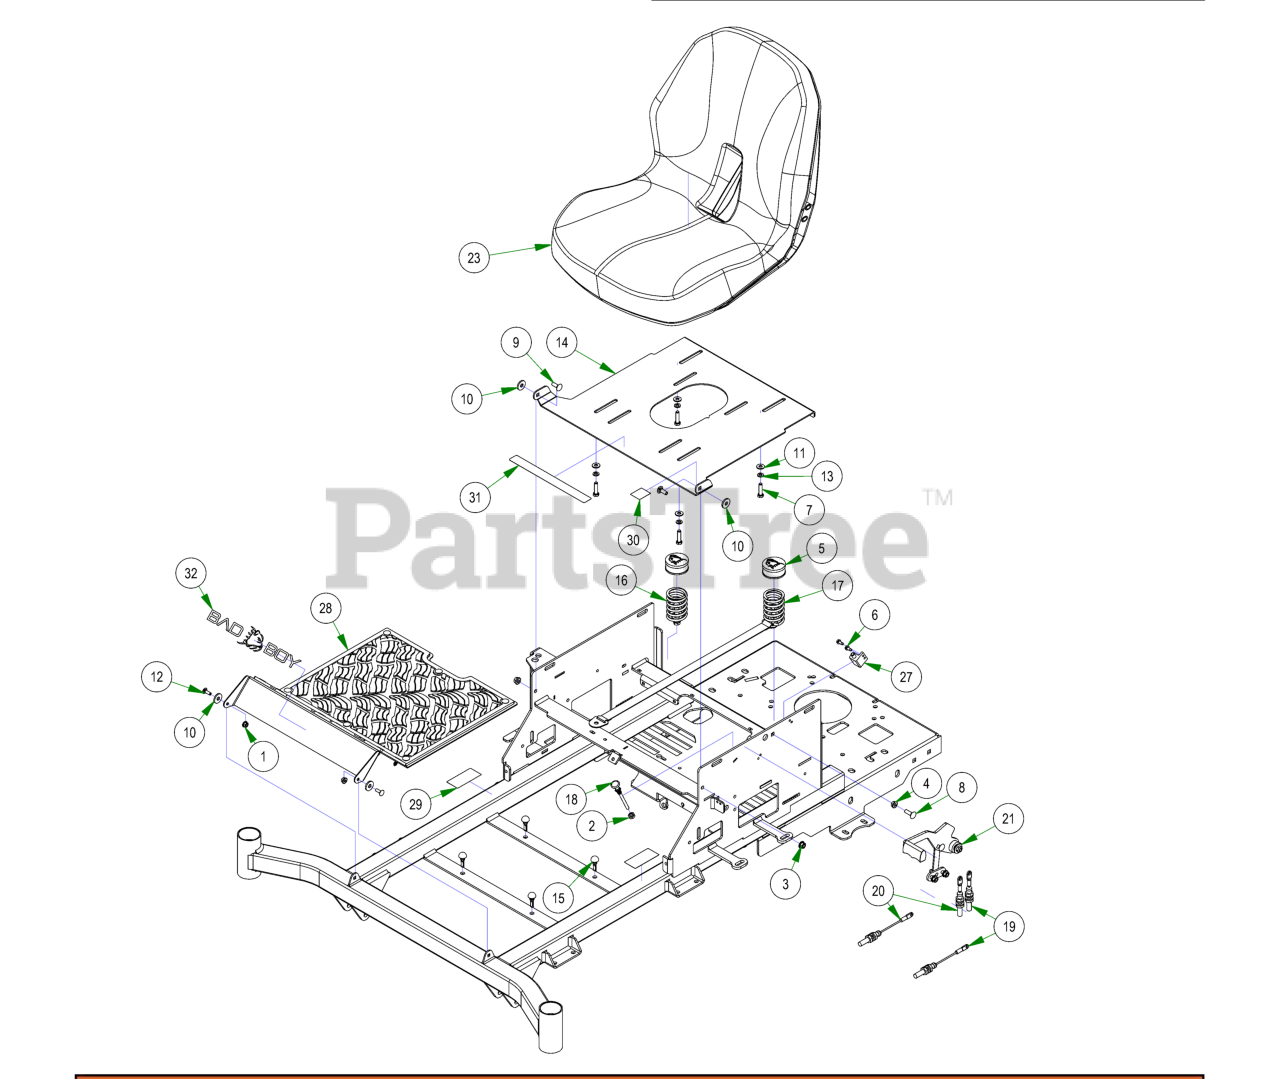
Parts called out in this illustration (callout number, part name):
1	1/4-20 NYL INSERT FLANGE LOCKNUT ZINC
2	3/8-24 HEX NUT ZINC YELLOW
3	5/16-18 NYLON INSERT FLANGE LOCKNUT ZINC
4	5/16-18 HEX SERRATED FLANGE NUT HARD/ZINC
5	Spring Cap Cover
6	12-24 X 1/2 HEX WASHER UNLSOT F TCS ZINC
7	5/16-18 X 1-1/4 HEX C/S (GR.5) ZC
8	5/16-18 X 1 CARRIAGE BOLT (GR.8) ZINC
9	5/16-18 X 7/8 CARRIAGE BOLT ZINC
10	.360 ID X .983 OD X .120 THICK FLAT WASHER NYLON
11	1/4 USS FLAT WASHER (3/4 OD) ZINC
12	1/4-20 X 3/4 CARRIAGE BOLT (GR.5) ZINC
13	5/16 SPLIT LOCKWASHER ZINC
14	2022 Avenger Seat Plate
15	2023 Floor Board Rubber Bumper
16	Seat Spring Assembly
17	2022 Mav/HD seat spring assembly with strap
19	2021 Load Balanced Brake Cable 1
20	2021 Load Balanced Brake Cable 2
21	2021 Load Balanced Brake Handle Assembly
22	2024 MZ-Avenger 54-60 Frame
23	2022 Avenger Seat
24	Seat Switch
25	Avenger Seat Cover
26	Water Proofing Protection
27	Safety Switch
28	2020 MZ AVEN Floorboard Assembly
29	2018 LH/RH Steering Control Decal Roll
30	2018 MZ/Magnum/ZT/MAV/Comp Out Brake Decal
31	Outlaw Warning Decal
32	Flying Bulldog Front Bumper Decal
